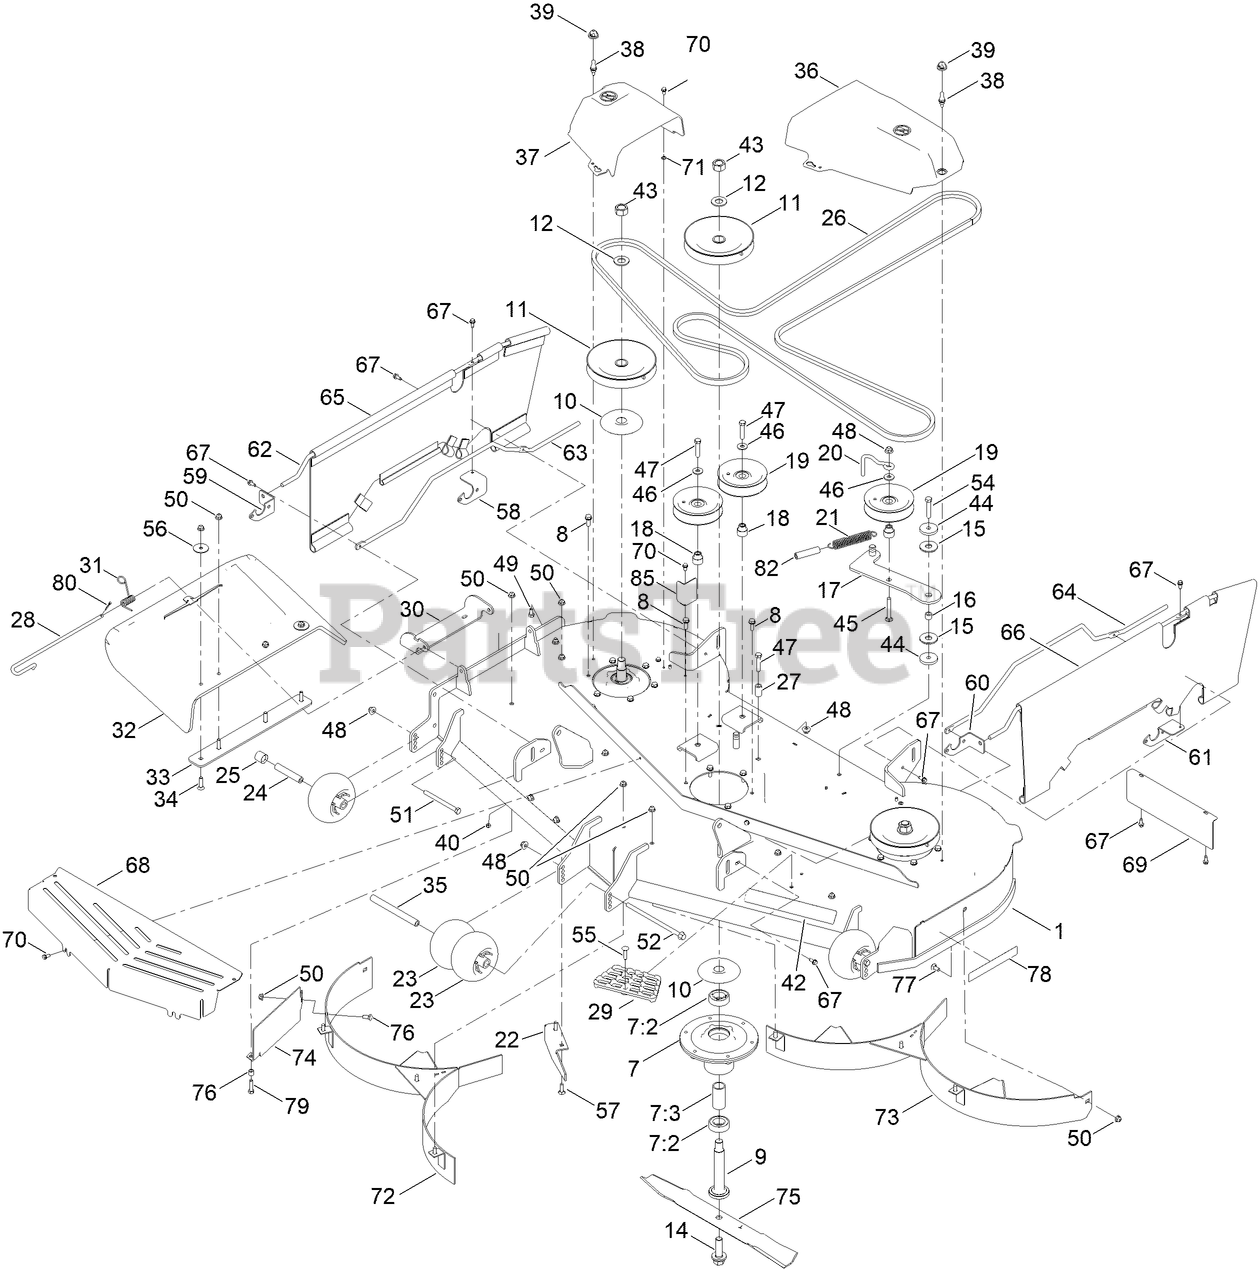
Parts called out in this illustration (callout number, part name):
1	60 IN DECK DECAL ASM
7	SPINDLE ASM
7:2	BEARING-BALL
7:3	SPACER-BEARING
8	SCREW-TAPTITE
9	SHAFT-SPINDLE
10	SHIELD-BEARING
11	PULLEY
12	WASHER
14	SCREW-BLADE
15	WASHER-FRICTION, COMPOSITE
16	SPACER
17	IDLER ARM ASM
18	BUSHING-IDLER
19	PULLEY-IDLER, FLAT
20	GUIDE-BELT, IDLER
21	SPRING-EXTENSION
22	BAFFLE-CUTOFF
23	ROLLER-SCALP, ANTI
24	TUBE-SPANNER
25	SPACER-AXLE, REAR
26	BELT-V
27	SPACER-FENDER
28	PIN-CHUTE
29	STEP-DECK
30	BRACKET-DEFLECTOR, UPPER
31	SPRING-TORSION
32	DEFLECTOR - MOLDED
33	PLATE-DEFLECTOR
34	BOLT-CARRIAGE
35	SPACER-WHEEL
36	COVER-BELT, LH
37	COVER-BELT, RH
38	STUD-BALL
39	GROMMET-BALL
40	NUT-LOCK
42	DECAL - IRON FORGED
43	NUT-HEX
44	WASHER-PLAIN
45	SCREW-CARR
46	WASHER-HARDENED
47	SCREW-HH
48	NUT-HF, NI
49	SCREW-HH
50	NUT-HF
51	SCREW-HH
52	SCREW-HF
54	HHCS 3/8-16 X 2, GR5, CZ
55	BOLT-CARRIAGE
56	WASHER-FLAT
57	SCREW-CARR
58	BRACKET-FRENCH GUARD
59	BRACKET-FRENCH GUARD
60	BRACKET-FRENCH GUARD
61	BRACKET-FRENCH GUARD
62	ROD-FRENCH GUARD
63	ROD-FRENCH GUARD
64	ROD-FRENCH GUARD
65	GUARD ASM-SIDE, POLY KNIT
66	GUARD ASM-SIDE, POLY KNIT
67	SCREW-HWH
68	BRKT-SHIELD, FRONT
69	PLATE-GUARD REAR
70	SCREW-HWH
71	NUT-RETAINING
72	BAFFLE-RH
73	BAFFLE-LH
74	GUARD-BAFFLE
75	BLADE-MULCH, 20.50 INCH
76	SPACER
77	BOLT-CARR
78	DECAL-RECYCLER
79	SCREW-HH
80	PIN-COTTER
82	HOSE-BREATHER
85	BRACKET-GUARD, CE
